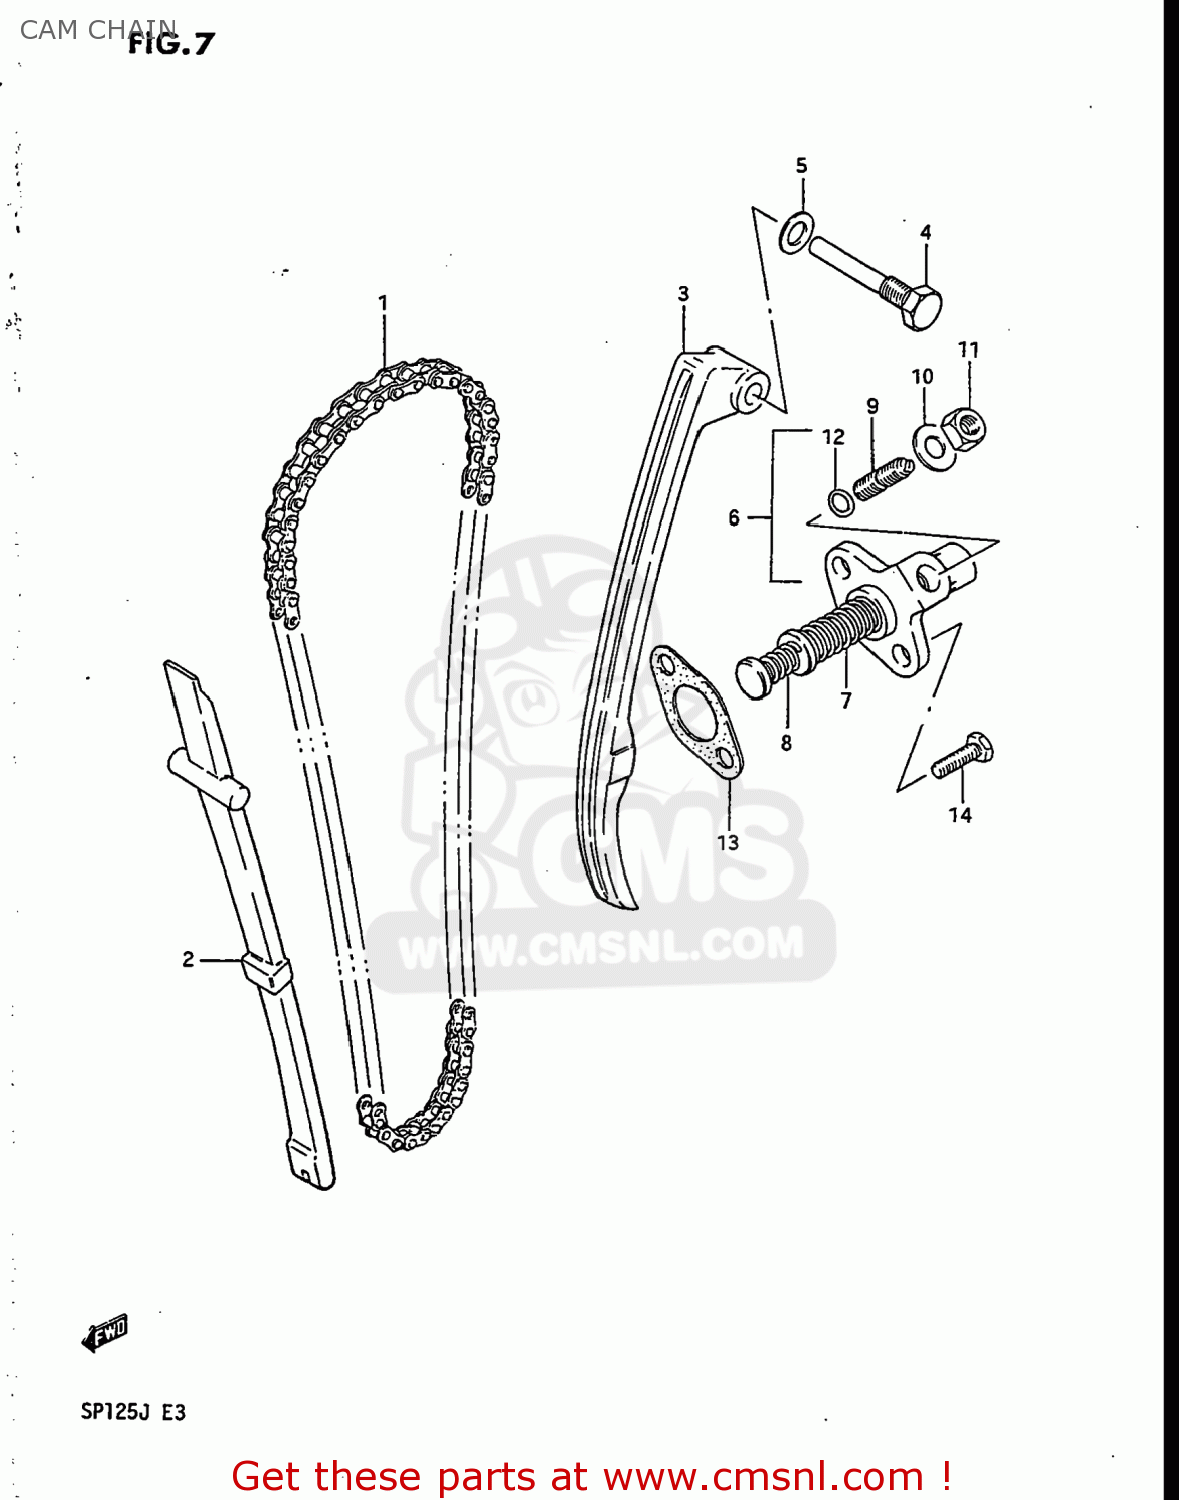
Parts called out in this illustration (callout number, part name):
1	CHAIN,CAMSHAFT DRIVE
2	GUIDE,CAM CHAIN
3	TENSIONER,CAM CHAIN
4	BOLT,CAM CHAIN TENSIONER
5	GASKET 8.2X14X1 (NAS)
6	ADJUSTER ASSEMBLY,TENSIONER
7	SPRING
8	SPRING
9	SCREW
10	WASHER
11	NUT
12	O RING(D:1.9,ID:5.7)
13	GASKET,TENSIONER ADJUSTER (NAS)
14	BOLT
